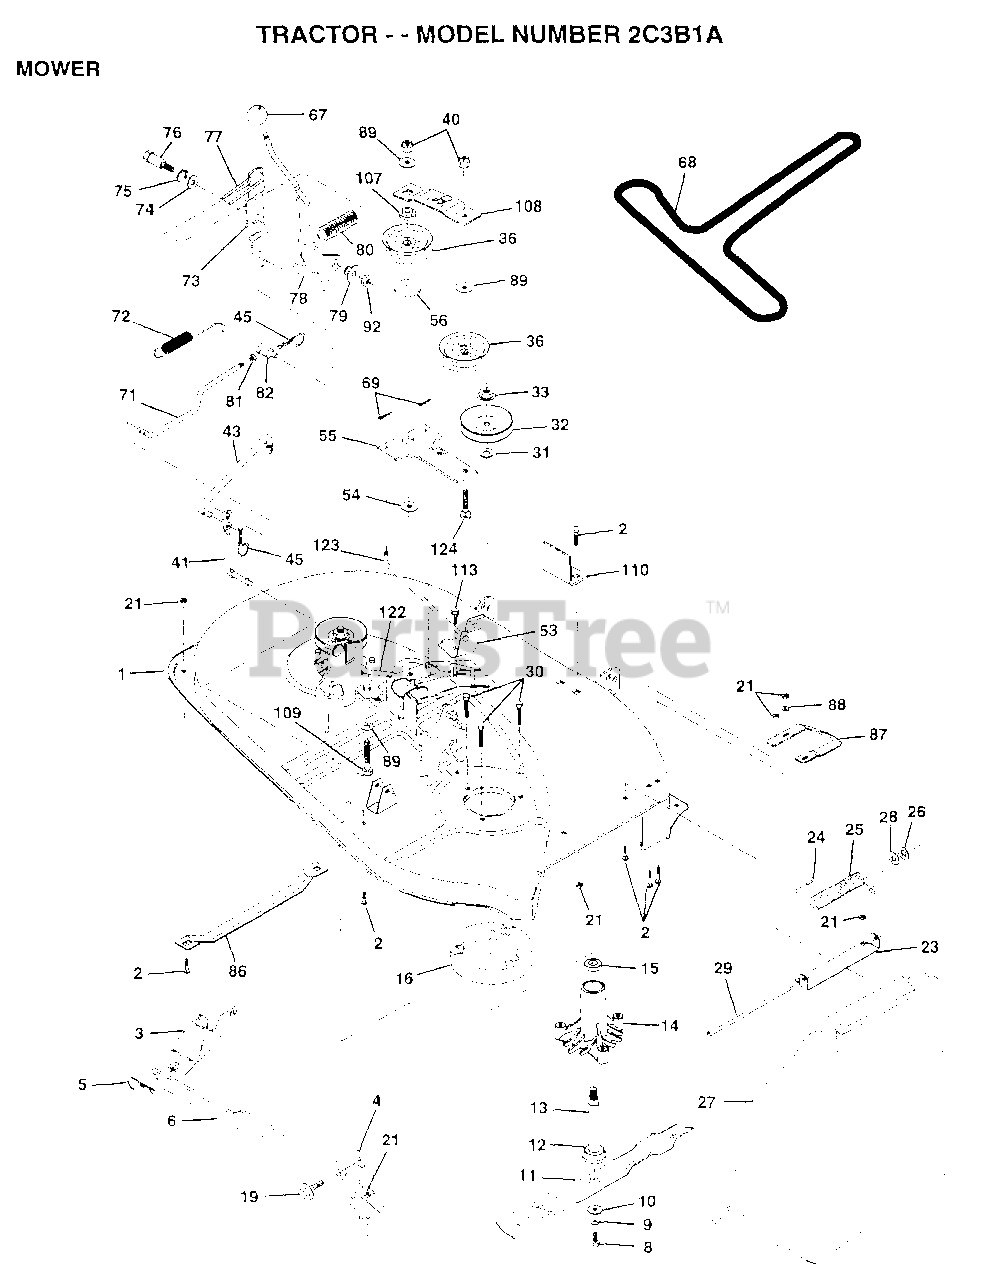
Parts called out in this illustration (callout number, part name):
2	BOLT
3	BRKT ASM SWAY BAR
4	BRKT DECK SW BAR
8	BLADE BOLT
10	WASHER.HARD.BLADE
11	"BLADE.38"" HIPERF"
12	BEARING.BALL
14	HSG ASM MANDREL
15	BEARING
16	STRIPPER RND MWR
19	BOLT SHD 5/16-18
23	BRKT DEFLECTOR
24	CAP-SLEEV(107627)
25	SPRING.(150051)
26	NUT PUSH M
28	WASHER
29	ROD-HINGE T
31	WASHER
36	FLAT IDLER PULLEY
41	PIVOT ROD
43	CLUTCH ROD SECOND
45	RETAINER M (5 2)(3 2)
53	BRAKE ASM
54	HARDENED WASHER
55	IDLER ARM ASSY
67	KNOB T(3/8 HOLE)
68	BELT.V.T-PATH
71	ROD CLUTCH 38/42
72	RETURN SPRING
73	CLUTCH ARM SECOND
74	WASHER
75	RING
76	SHOULDER BOLT
77	SPRING KEEPER
79	BUSHING
81	NUT
82	TRUNION ADJ
86	RUNNER-LH M
87	RUNNER RH
88	WASHER M
89	WASHER GT
92	NUT
107	RETAINER SPACER
108	IDLER ARM STIFF
109	BOLT
110	UPSTOP DECK FT 38
113	SCREW
122	BRAKE ROD LH
123	BRAKE ROD RH
124	BOLT
